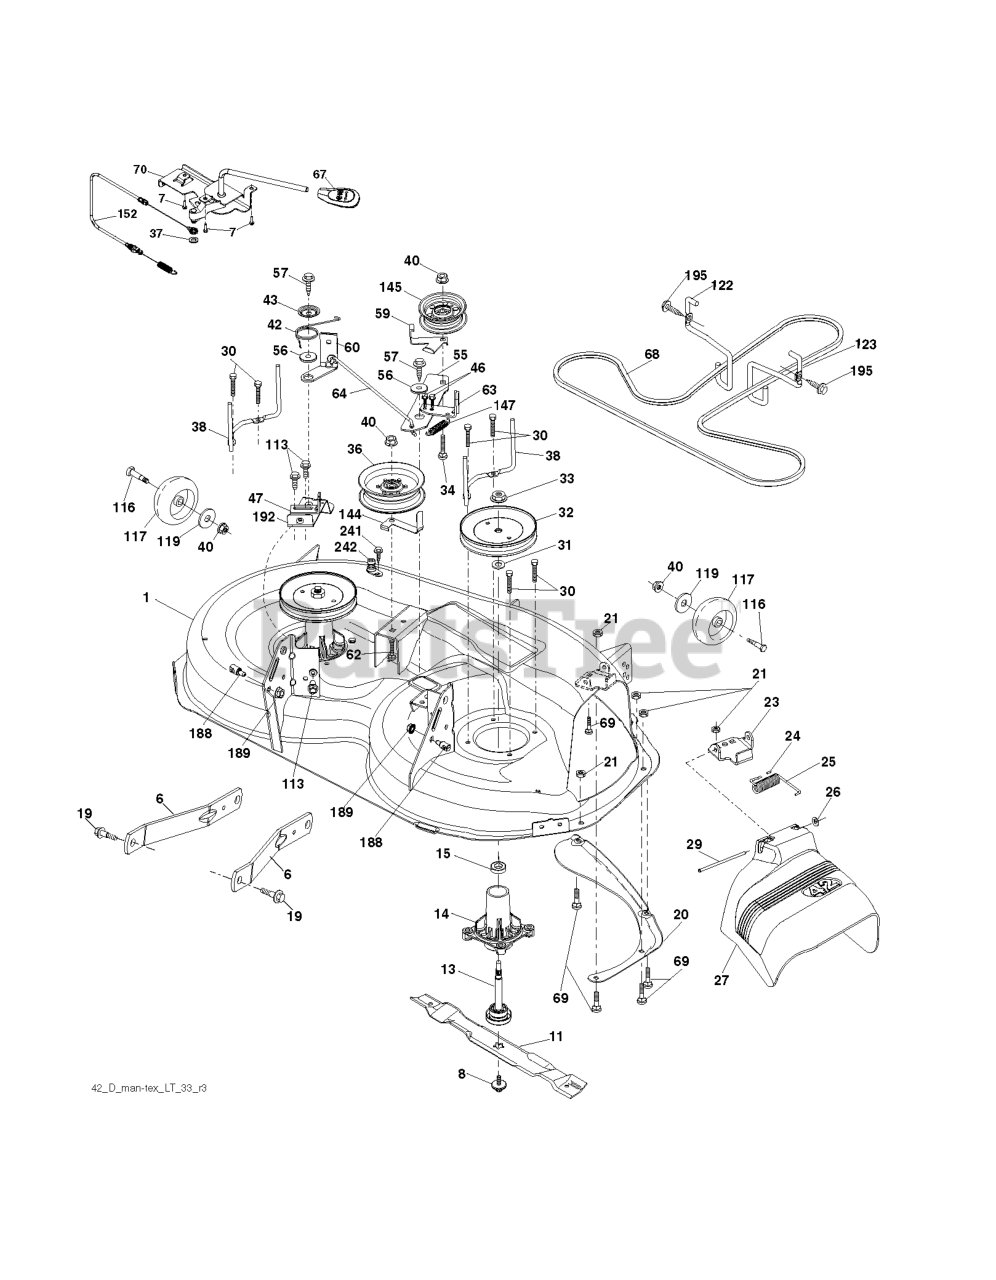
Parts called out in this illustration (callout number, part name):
1	DECK.WELDMENT.42"PAINT
6	ARM.SUSPENSION.MOWER.R
7	SCREW.#10 X 0.750.BOS
8	BOLT.WASHER.ASM.7/16-2
11	42" HI-LIFT BLADE
13	SHAFT.ASM.MDRL.N/GREASE.38
14	RP.HOUSING.MANDREL.4PT.
19	BOLT.SHOULDER
20	BAFFLE.VORTEX
21	LOCKNUT
23	BRKT.DEFLECTOR.38"2005+
24	CAP-SLEEVE LT
25	SPRING.TORSION.DEFLECT
26	NUT PUSH M
27	SHIELD.DEFLECTOR.MOWER.42"BLAC
29	ROD.HINGE
30	SCREW, WASHER HEAD
31	WASHER.SPACER.MANDREL
32	PULLEY.MANDREL.5.438.PD
33	NUT.FLANGE.LOCK.TOP
34	BOLT.3/8-16X1.50
36	PULLEY.IDLER.2006
37	WASHER
38	KEEPER.BELT.MANDREL.PULLEY
40	NUT LOCK FLG 3/8-16 UNC
42	SPRING.TORSION.BRAKE
43	SRPING.TORSION.RETAINE
46	SCREW.1/4-20X5/8
47	BRKT.CLUTCH.CABLE
56	SPACER.RETAINER
57	SCREW 3/8-16X1
59	GUARD, BELT
60	ARM BRAKE MOWER
63	ARM BRAKE MOWER
64	LINKAGE.BRAKE.ASM.ZINC
67	HANDLE.CLUTCH.CABLE.LT
68	BELT.DECK.DRIVE.42"
69	BOLT
70	CLUTCH.ASM.CABLE.HUSQ.TEX
113	BOLT.5/16HEX.WHS.HD
116	BOLT.SHOULDER.3/8-16X3-5/8.
117	RP WHEEL. GUAGE RALLY
119	WASHER
122	KEEPER BELT ENGINE LH
123	KEEPER BELT RH
144	KEEPER.BELT.MOWER
145	PULLEY.IDLER.48"PRIMARY
147	RETURN SPRING
152	CABLE.CLUTCH.CABLE.W/SPRING
188	STUD.FASTNER.W/ANTI-ROTATE
189	NUT LOCK HEX FLANGE 5/16-18
192	BRKT.BRAKE.STAND.LH.
195	SCREW, 3/8-16X3/4
241	SCREW.TT.#10-32X.5.3/8.FLANGE
242	PORT.WASHOUT
